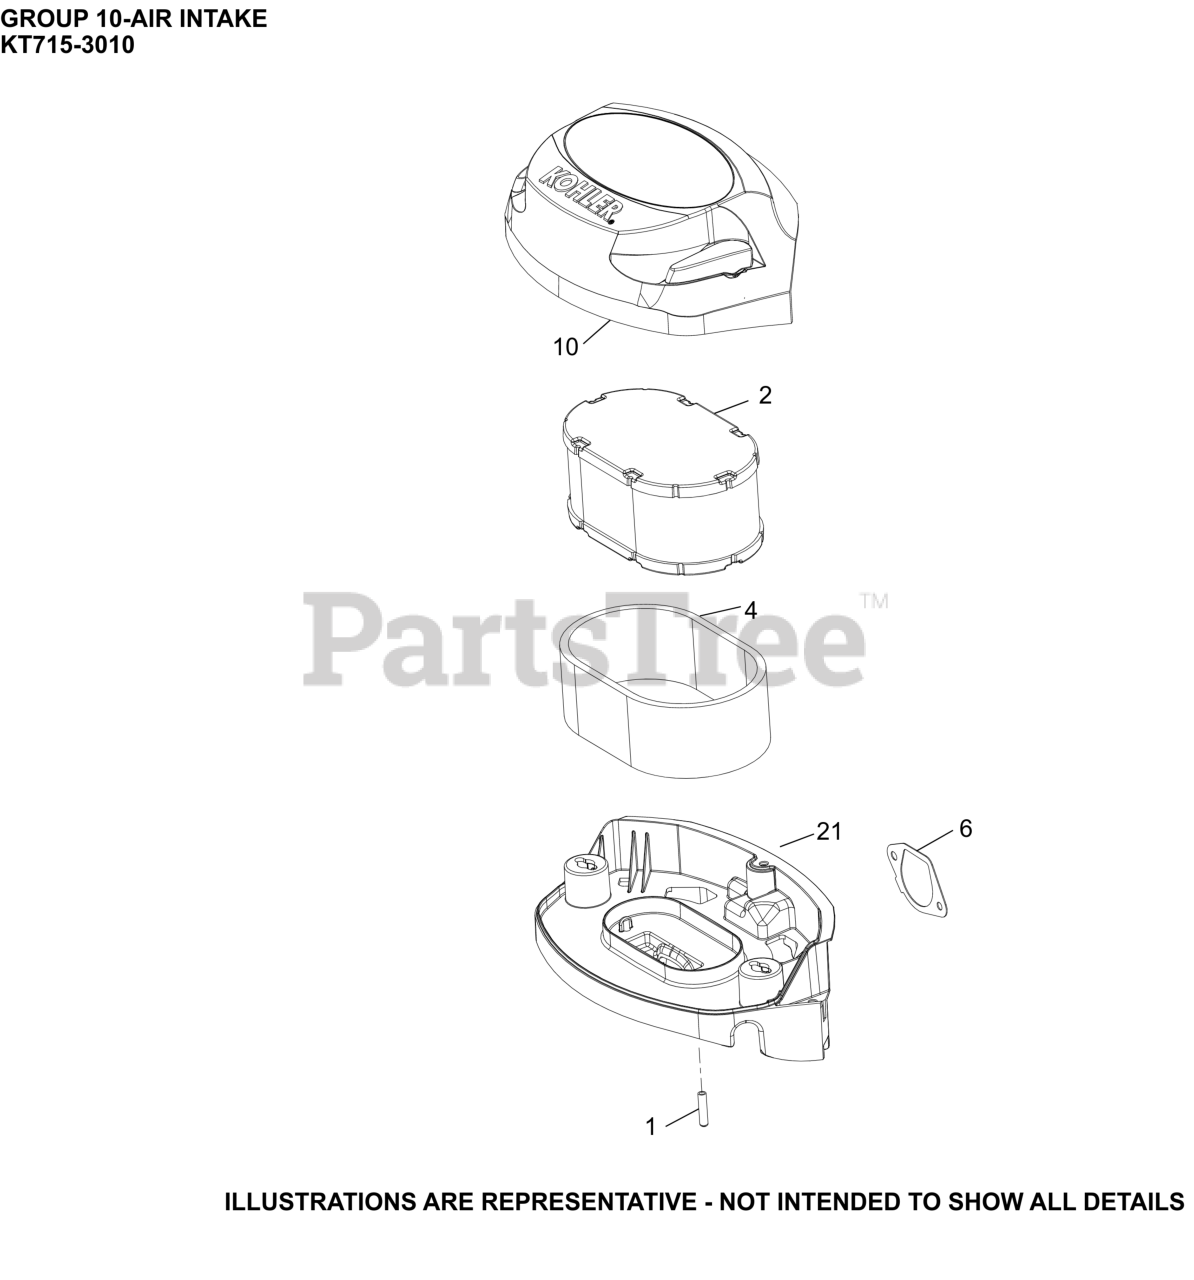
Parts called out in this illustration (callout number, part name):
1	CAP, MASKING
2	ELEMENT, AIR FILTER
4	ELEMENT, PRE-CLEANER
6	GASKET, AIR CLEANER BASE
10	COVER ASSY, AIR CLEANER
21	BASE ASSEMBLY, AIR CLEANER
